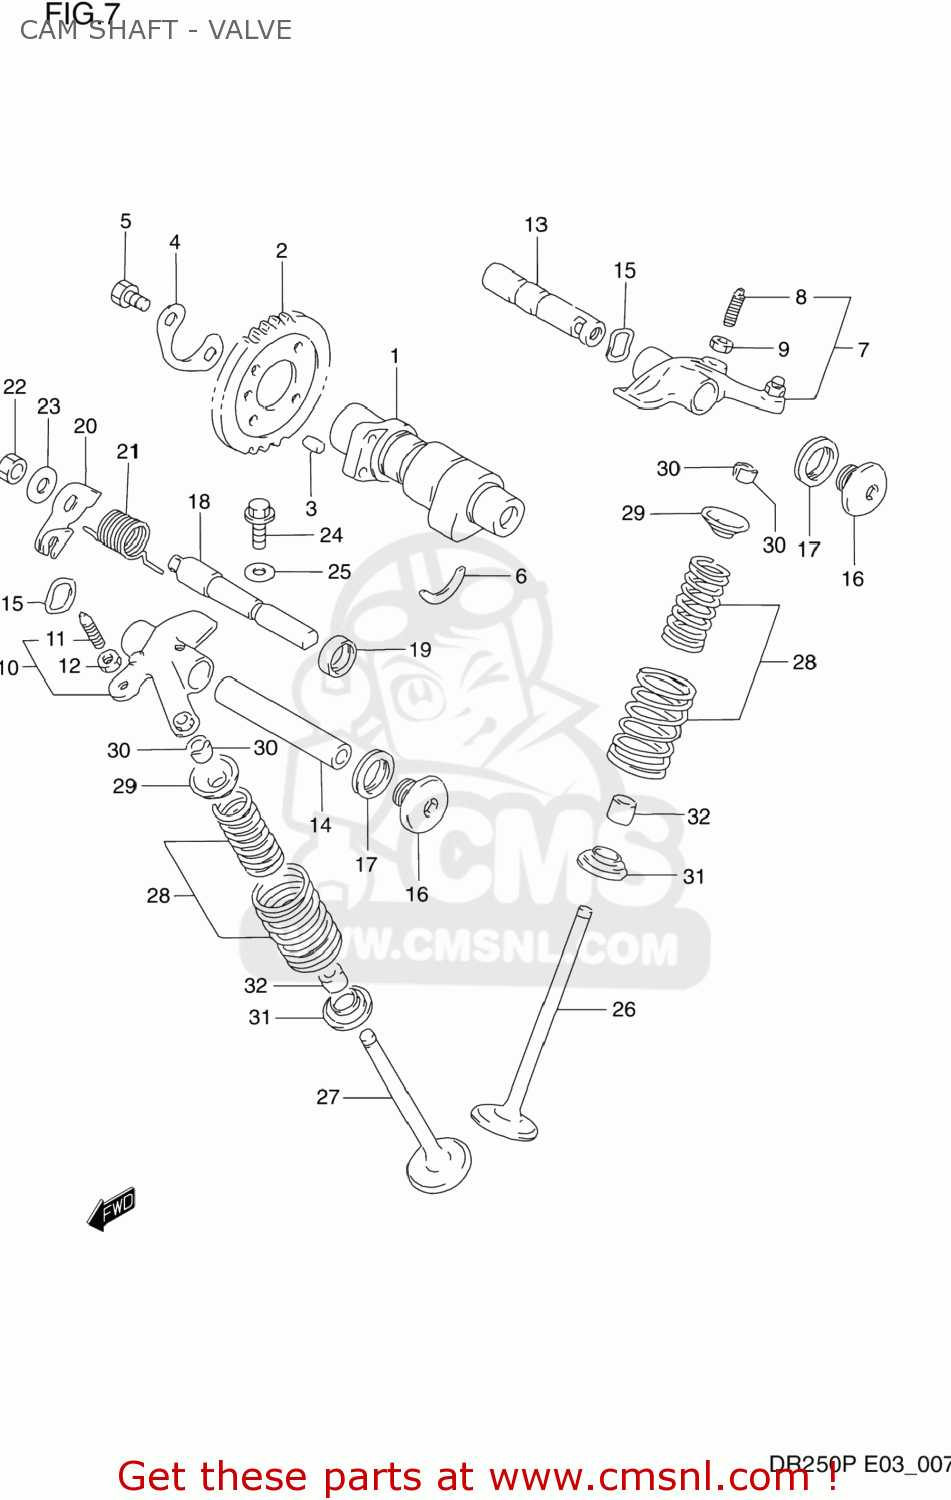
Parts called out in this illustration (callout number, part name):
1	CAMSHAFT
2	SPROCKET,CAMSHAFT INTAKE
3	PIN(5X8)
4	WASHER,SPROCKET
5	BOLT(6X10.5)
6	C RING
7	ARM,VALVE ROCKER INTAKE
8	SCREW,TAPPET ADJUSTING
9	NUT,ADJUSTING
10	ARM,VALVE ROCKER EXHAUST
11	SCREW,TAPPET ADJUSTING
12	NUT,ADJUSTING
13	SHAFT,VALVE ROCKER ARM INTAKE
14	SHAFT,VALVE ROCKER ARM EXHAUST
15	WASHER
16	PLUG,14X12
17	GASKET(14X19.2X2) (NAS)
18	SHAFT,DECOMPRESSION
19	SEAL,OIL(10X17X6)
20	LEVER,DECOMPRESSION SHAFT
21	SPRING
22	NUT 8MM
23	WASHER
24	BOLT
25	GASKET(6.4X11.5X0.8) (NAS)
26	VALVE,INTAKE
27	VALVE,EXHAUST
28	SPRING SET,VALVE
29	RETAINER,VALVE SPRING
30	COTTER VALVE
31	SEAT,VALVE SPRING
32	SEAL,OIL(5X10X9.7)
